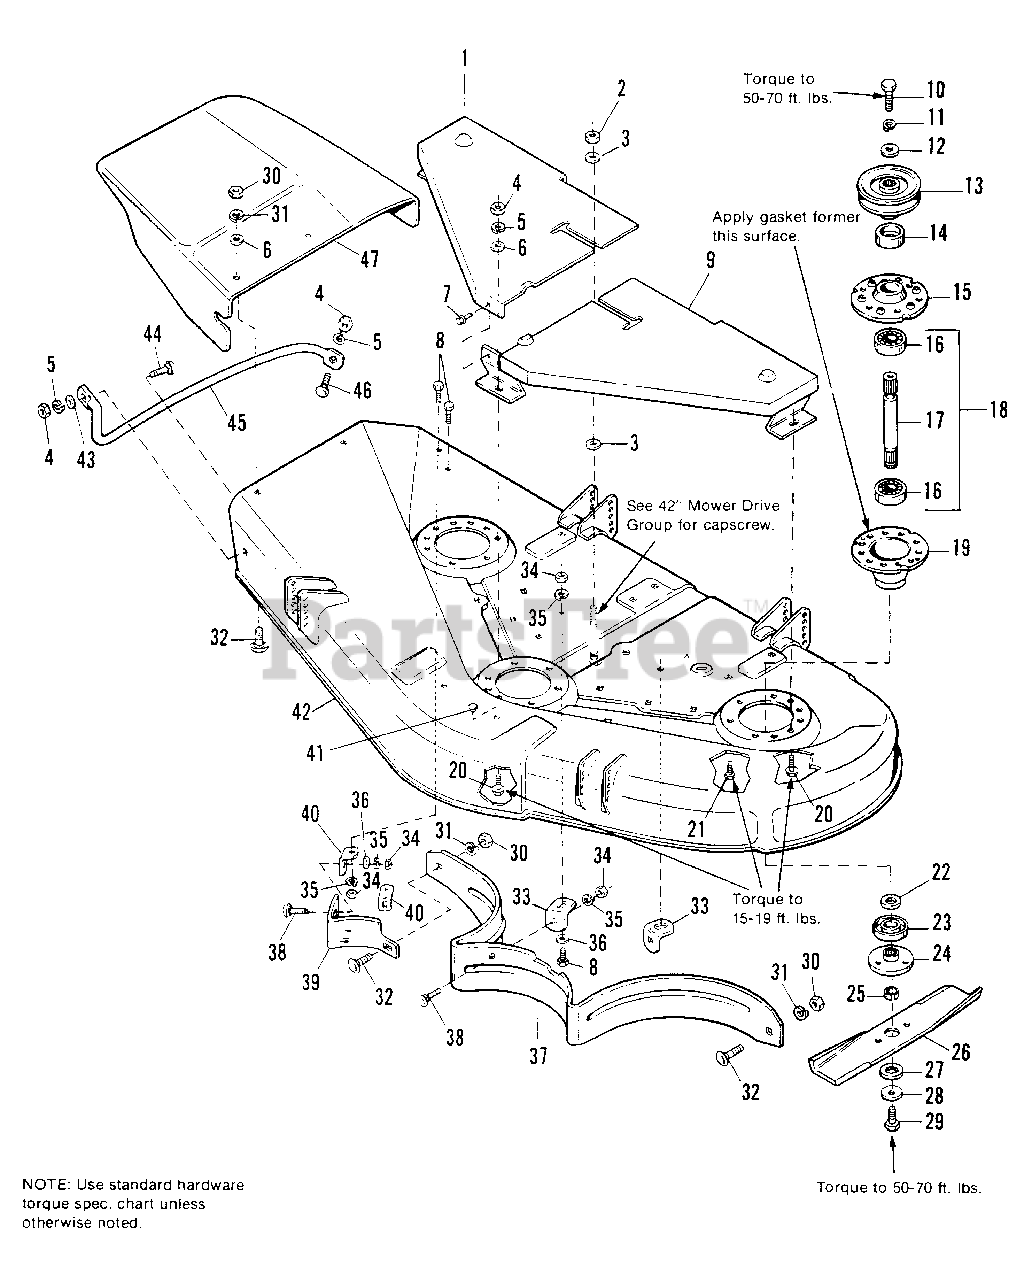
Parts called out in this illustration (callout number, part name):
1	COVER ASSY., Belt, R.H.
2	NUT, Hex, Jam, 3/8-16
4	NUT, 5/16-18
5	LOCKWASHER, 5/16
6	WASHER, 3/8
7	SCREW, Taptite, 1/4-20 x 3/8
8	CAPSCREW, Hex, 1/4-20 x 7/8
9	COVER ASSY, Belt, L.H.
10	CAPSCREW, Hex, 7/16-14 x 1-3/4
11	LOCKWASHER, 7/16
12	WASHER, 7/16
13	PULLEY ASSY., Arbor
14	SHIELD, Bearing Upper, Arbor
15	HOUSING, Top (Arbor)
17	SHAFT, Arbor (Incl. Ref. No. 25)
18	SHAFT & BEARING ASSY. (Incl Ref. Nos. 16 & 25)
19	HOUSING, Bottom (Arbor)
20	SCREW, Taptite, 5/16-18 x 1
21	SCREW, Taptite, 5/16-18 x 3/4
22	WASHER, Shim
23	SHIELD, Grass
24	ADAPTOR, Blade
25	COLLAR, Mower Arbor
27	WASHER, Spline
28	WASHER, Spring
29	CAPSCREW, Hex, 7/16-14 x 1
30	NUT, 3/8-16
31	LOCKWASHER, 3/8
32	BOLT, Carriage, 3/8-16 x 3/4
33	CLIP, Baffle
34	NUT, 1/4-20
35	LOCKWASHER
36	WASHER, 1/4
37	BAFFLE
38	CARRIAGE BOLT, 1/4-20 x 5/8
39	BAFFLE, Discharge
40	CLIP, Baffle
41	PLUG, Plastic
42	HOUSING ASSY., 42" Mower
43	WASHER, 5/16
44	CARRIAGE BOLT, 5/16-18 x 1
45	GUARD, Mower Discharge
46	CARRIAGE BOLT, 5/16-18 x 3/4
